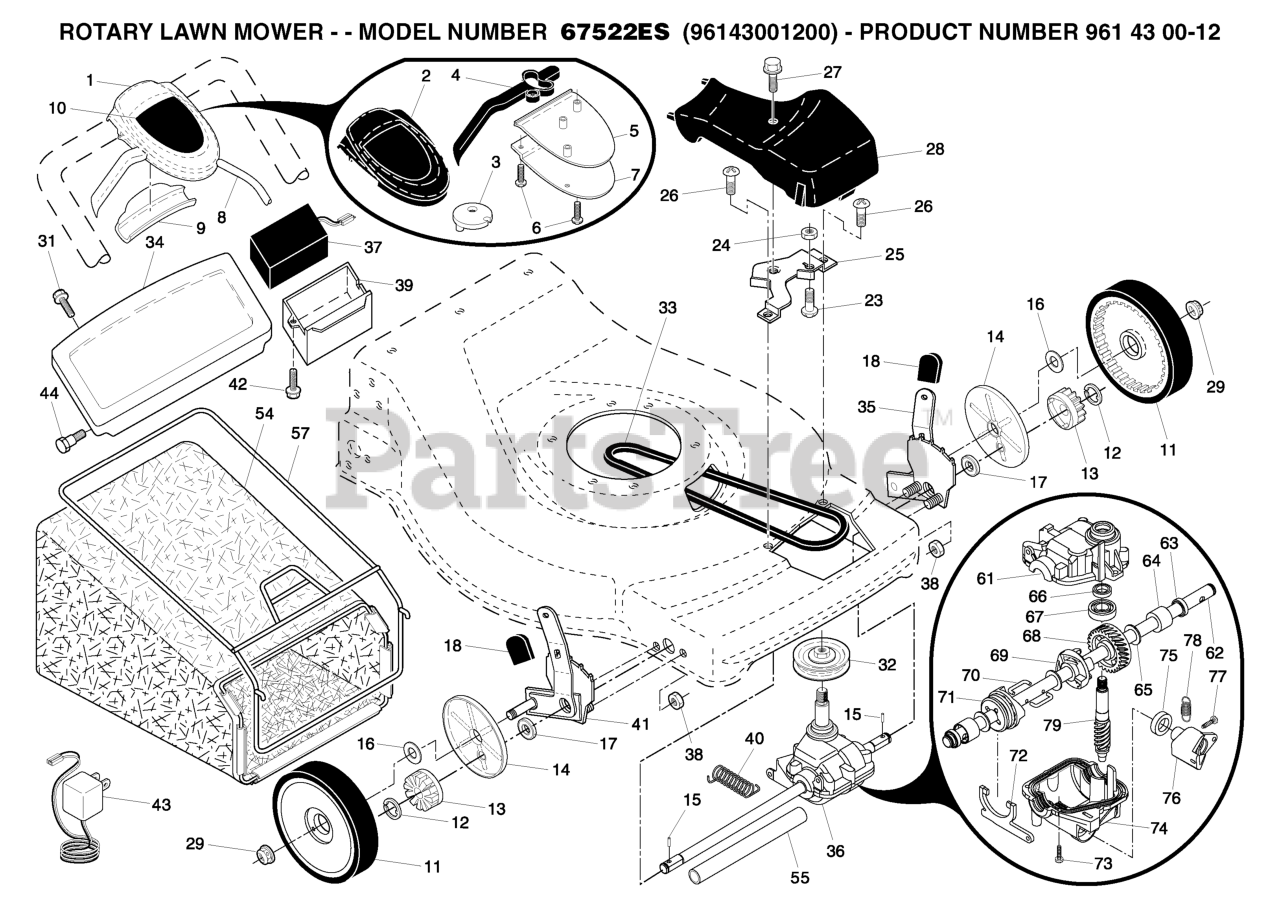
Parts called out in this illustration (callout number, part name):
1	RP CONTROL.DR.EZ
2	CASE.TOP.GRAY
3	PULLEY.CAM.DRIVE.CONTROL.HV
4	LEVER, AUTOWALK DRIVE CONTROL
5	CASE BOTTOM
6	SCREW, PHILLIPS HEAD 10 X 5/8
7	BRACKET.DRIVE.CONTROL.MOUNT.BL
9	EZ WALK SNAP COVER PLATE
11	WHEEL.8X1.75.5SPK.RAD.GREY
12	E-RING 7/16 RE
13	PINION
14	COVER.DUST.WHEEL
15	PAWL.DRIVE
16	WASHER FLUT
17	BEARING
18	KNOB.DELUXE.GRAY
23	HINGE SCREW
24	NUT.HEX.FLANGE.1/4
25	BRKT.CABLE/BELT.GUARD.
26	SCREW.HEX.WSH
27	SCREW, HEX HD TAPPING #10-24 1
29	HEX FLANGE LOCKNT
31	SCREW.PAN.HEAD.#10
32	RP PULLEY.DRIVE.EZ
33	BELT.DRIVE.FG
34	PANEL.TRIM.21.FWGD
35	RP KIT.ADJUSTER.ASM.EZ
36	TRANSMISSION.22.FWGD
37	BATTERY WITH AMP CONECTOR AGM
38	LOCKNUT.NYLOC.1/4-20
39	BOX.BATTERY.TRIM
40	SPRING RETURN
41	KIT.ADJUSTER.AS.EZ RT
42	SCREW.HWH.13-16X.50
43	RP CHARGER.BATTERY
44	SCREW.SHOULDER.HH.10X.281X.6
55	DRV SHAFT TUBE PM
57	FRAME.GBAG.EZ.EMPTY
61	GEARCASE.HOUSING
62	OUTPUT.SHAFT.(12245)
63	SEAL.OUTPUT.SHAFT
66	SEAL INPUT SHAFT
68	GEAR.27.TEETH.WALK.MOWER
70	WIRE, FORMED (15966)
74	GEARCASE.HOUSING.LOWER
77	SCREW.LEVER.
79	SHAFT INPUT (13041)
